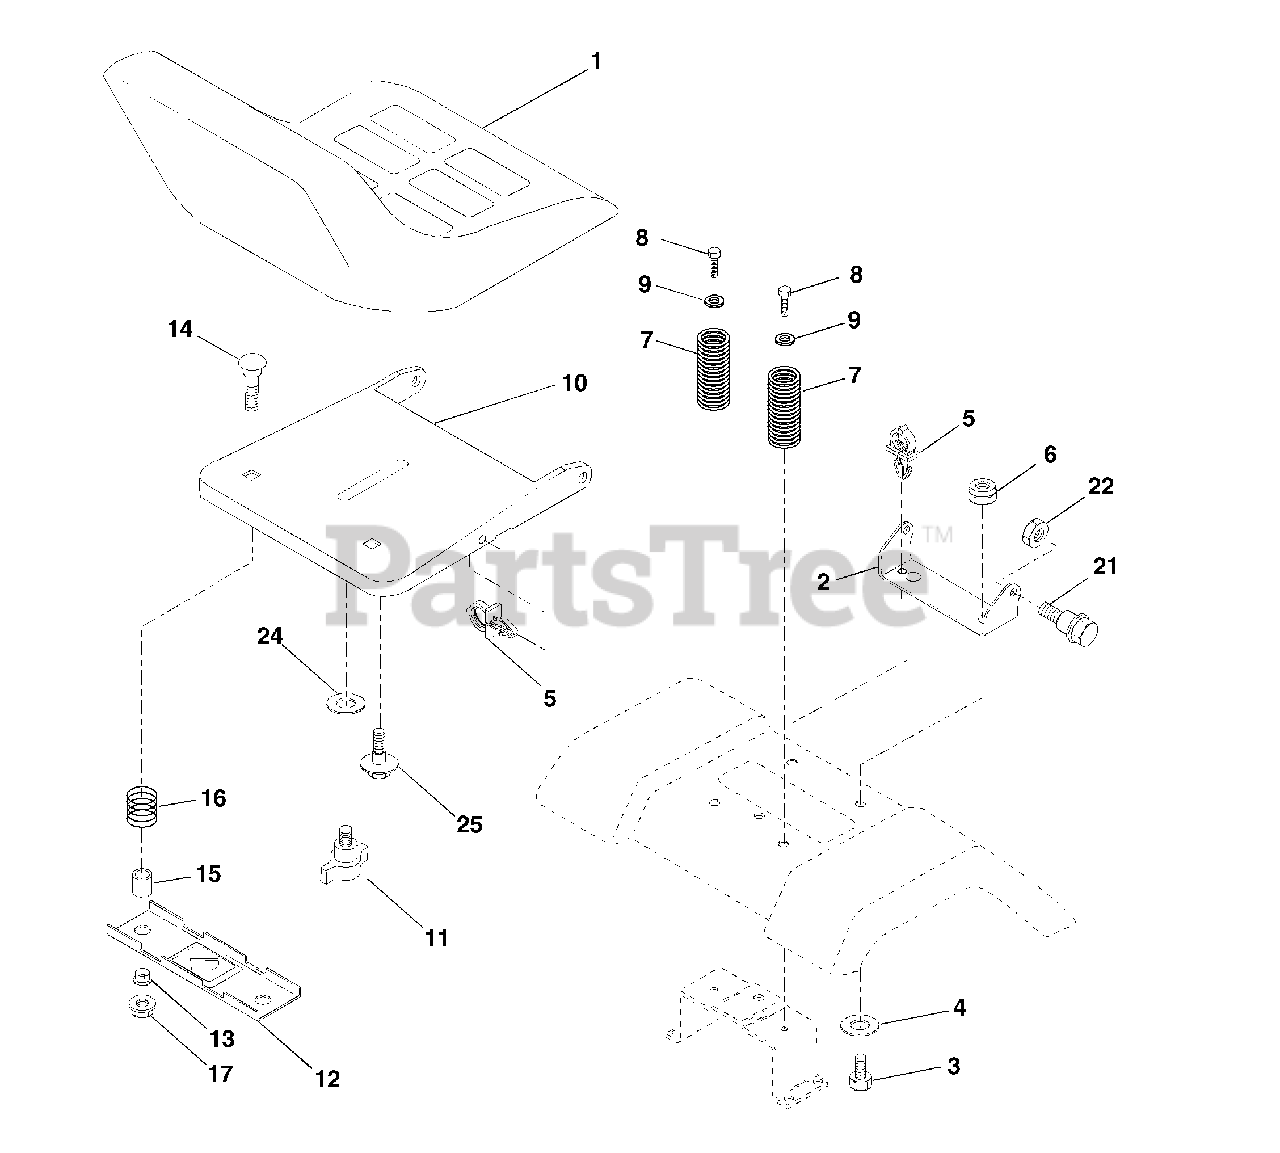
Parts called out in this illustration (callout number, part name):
1	Seat
2	Bracket Pivot Seat 8 720
3	Bolt Fin Hex 3/8-16 Unc X 1
4	Washer 13/32 X 1 X 10 Ga
5	Clip Push-In
6	Nut Hex w/Ins. 3/8-16 Unc
7	Spring Seat Cprsn 2 250 Blk Zi
8	Screw 3/8-16 X 1.5
9	Washer 13/32 X 1 X 14 Ga.
10	Pan Seat
11	Knob Seat
12	Bracket Mounting Switch
13	Bushing Snap Blk Nyl 50 Id
14	Bolt Rdhd Sqnk 1/4-20x1-1/2
15	Spacer Split 28x 88
16	Spring Cprsn
17	Nut Lock 1/4 Lge Flg Gr 5 Zinc
21	Bolt Shoulder 5/16-18 Unc
22	Nut Hex Lock W/Ins 5/16-18
24	Washer 17/32 X 1-3/16 X 12 Ga.
25	Bolt Shoulder 5/16-18 X 62
